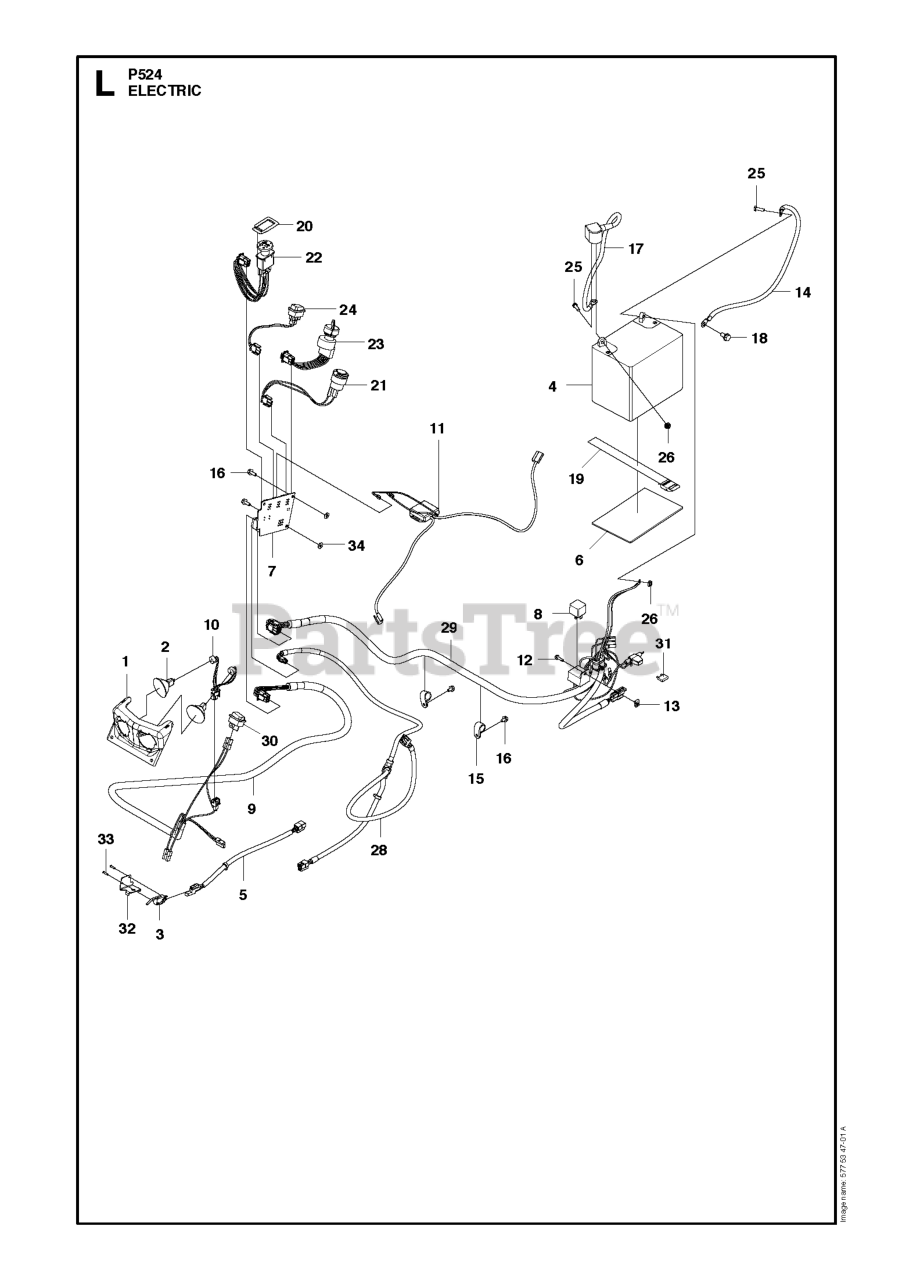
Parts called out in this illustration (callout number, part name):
3	MICRO SWITCH
5	WIRING
25	SCREW EHHM
31	FUSE 20AMP
